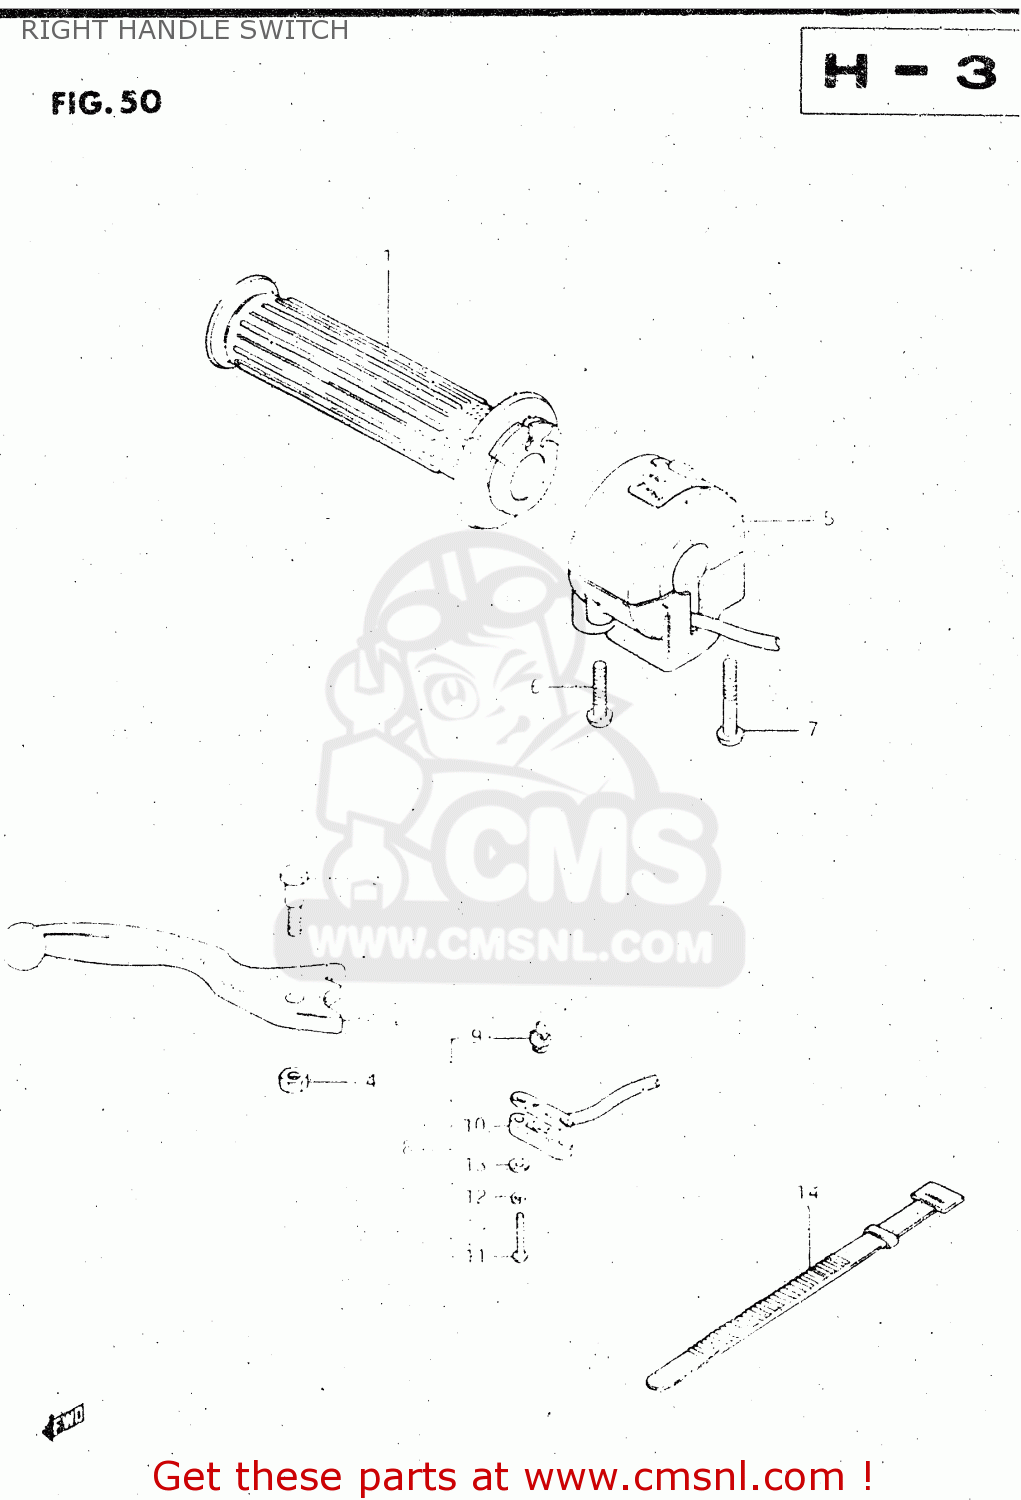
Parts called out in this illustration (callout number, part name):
1	GRIP,THROTTLE
2	LEVER,BRAKE
3	BOLT
4	NUT 6MM
5	SWITCH ASSY, HANDLE LH
6	SCREW
7	SCREW
8	SWITCH ASSEMBLY
9	CONTACT,SWITCH
10	COVER,FR BK TERMINAL BASE
11	SCREW
12	LOCK WASHER
13	WASHER
14	CLAMP(L:120)
